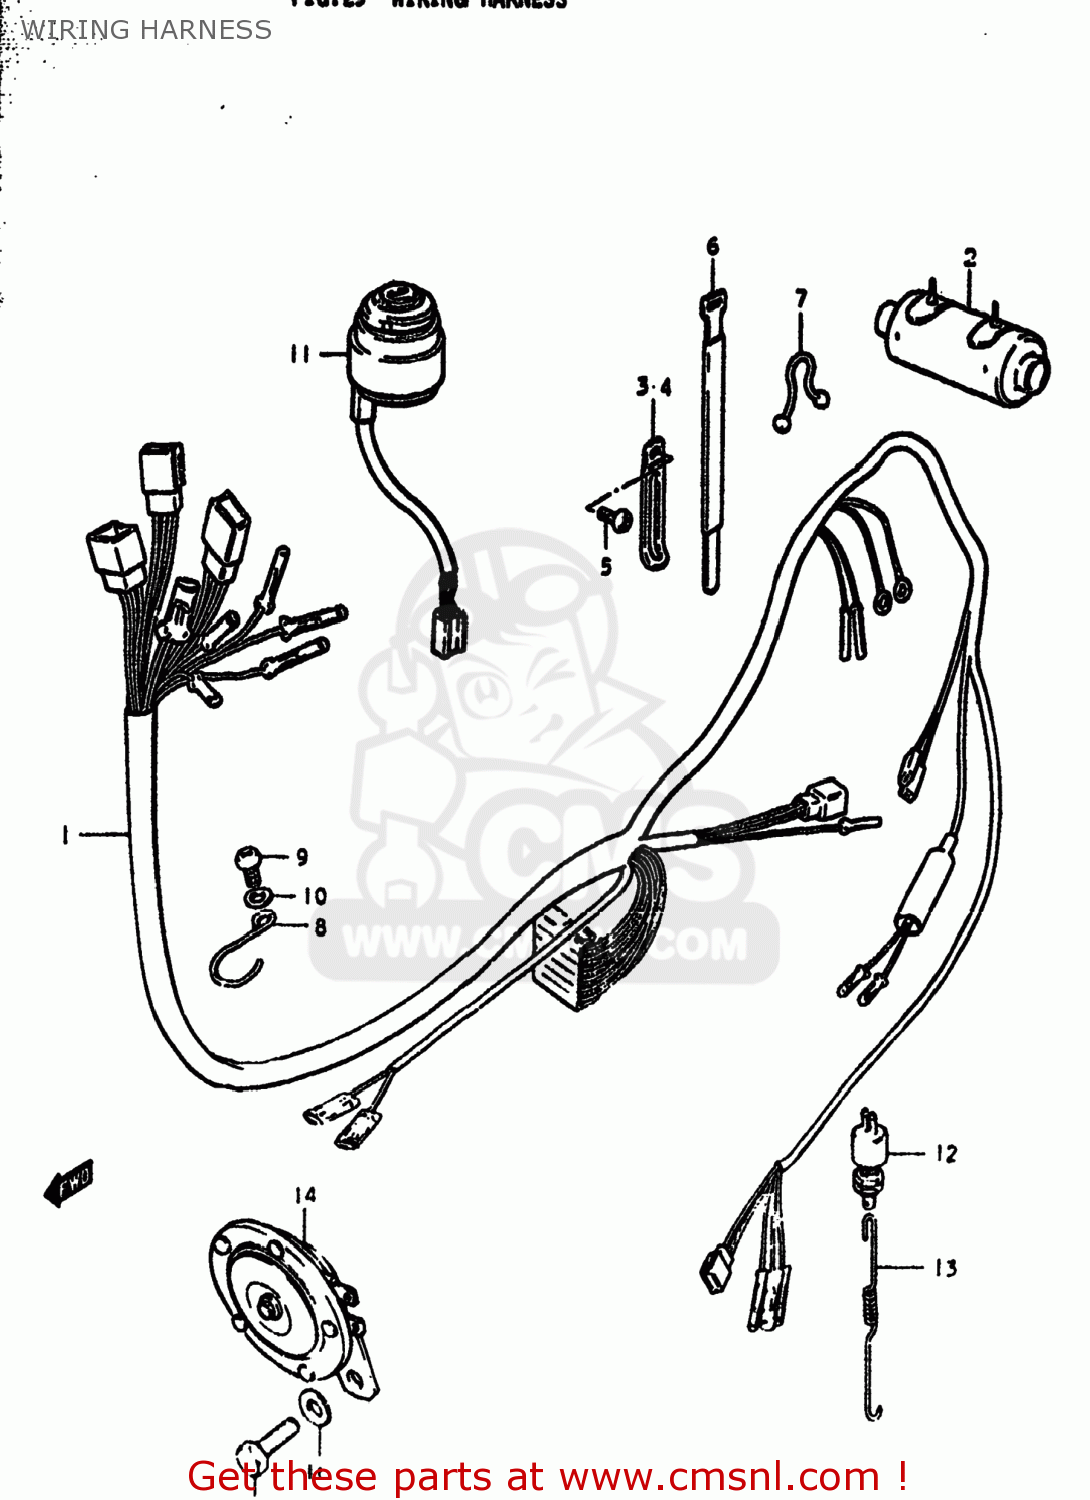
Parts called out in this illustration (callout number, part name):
1	HARNESS,WIRING
2	BOOT,WIRING HARNESS
3	CLAMP
4	CLAMP
5	SCREW
6	CLAMP
7	CLAMP
8	GUIDE,WIRING HARNESS
9	SCREW 6X12
10	WASHER 6MM
11	SWITCH ASSEMBLY,IGNITION
12	SWITCH ASSY,BRAKE LAMP
13	SPRING
14	HORN ASSY
15	BOLT 8X12
16	WASHER
